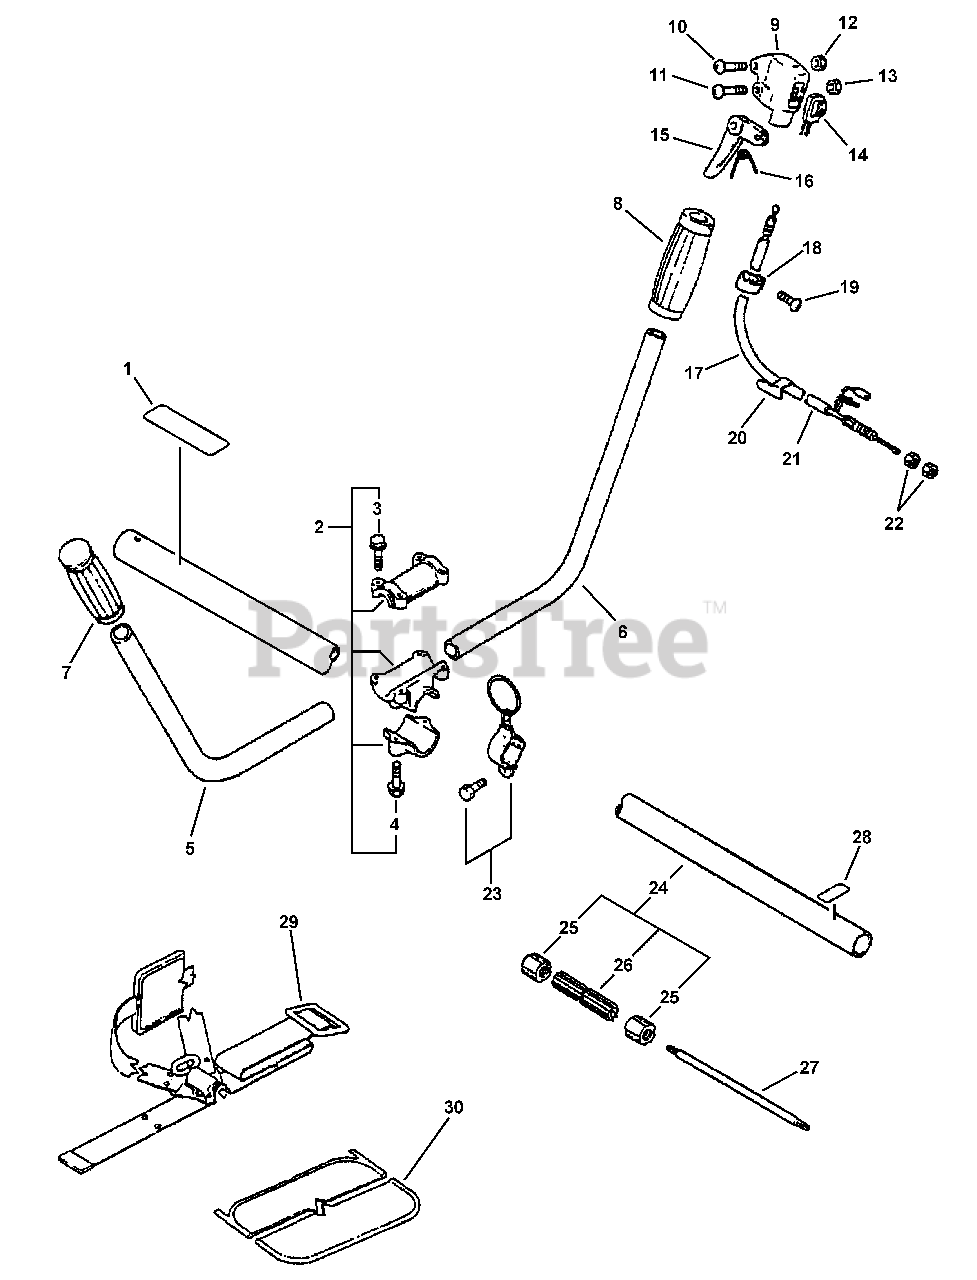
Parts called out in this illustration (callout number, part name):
1	Label, Caution
2	Handle Bracket Asy
3	Bolt 5x25
4	Bolt 6x30
5	Handle, Front - Left
6	Handle, Front - Right
7	Grip, Handle
8	Grip, Handle
9	Bracket, Throttle
10	Screw 5x25
12	Locknut 5
14	Switch, Ignition
15	Control, Throttle
16	Spring, Throttle Return
17	Cable, Throttle
19	Screw 5x10
20	Clip, Throttle Wire
21	Tube 10x11x750
23	Hook Asy
24	Driveshaft Housing Asy
25	Fixture, Liner
26	Liner, Flexible
27	Shaft, Flexible
28	Label, Location
29	Harness Asy
30	Pad, Waist
